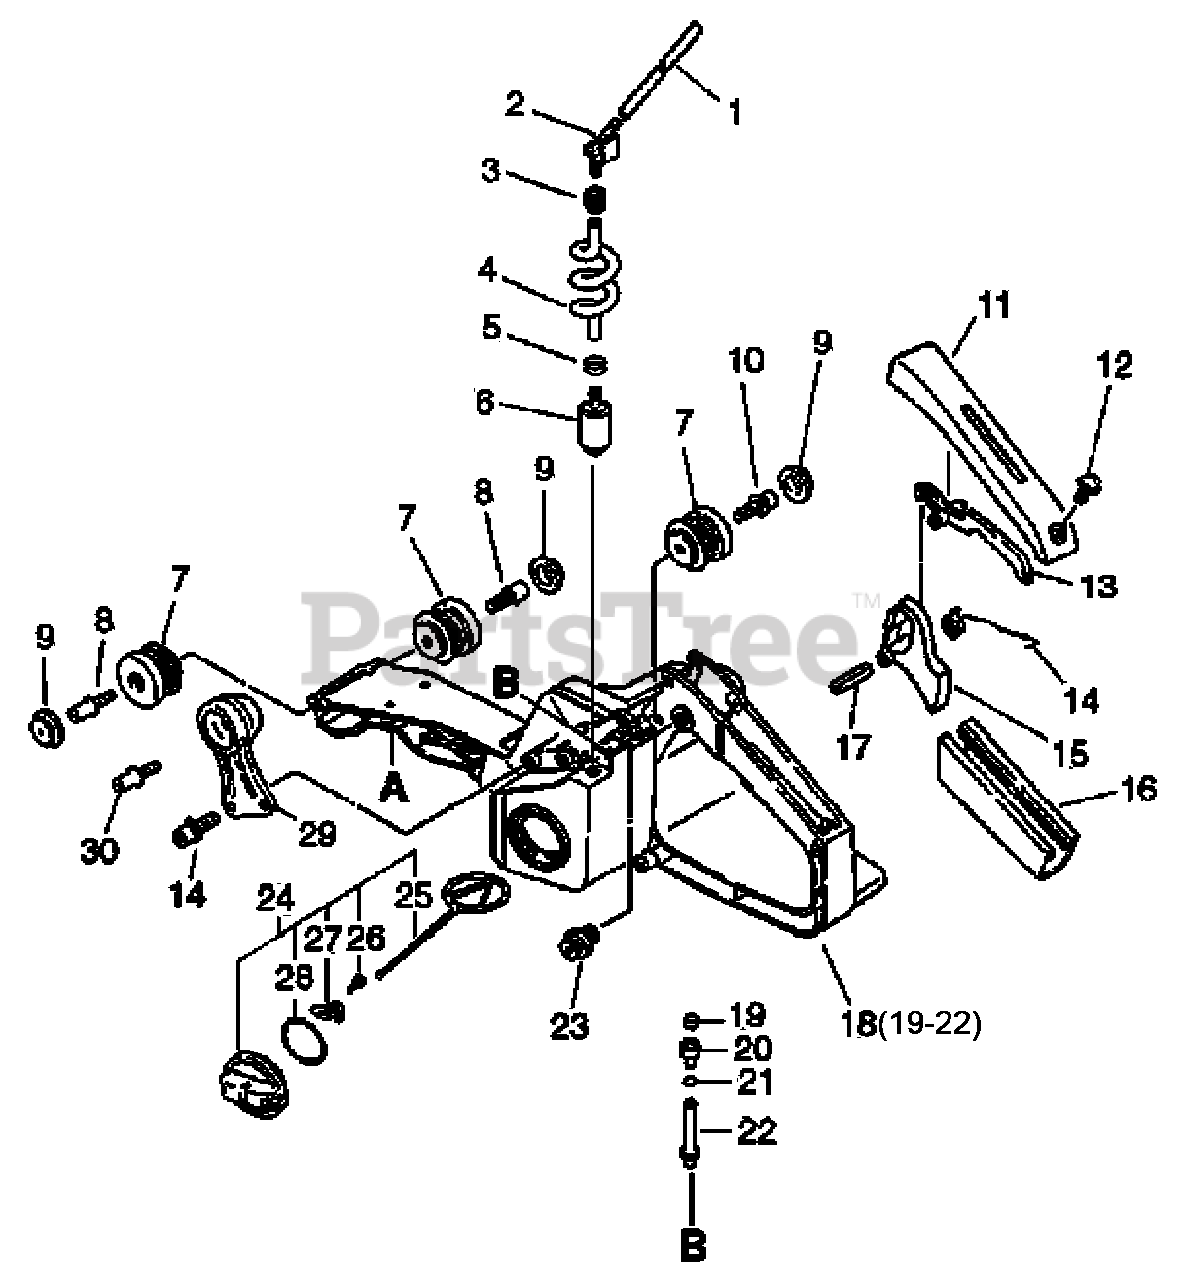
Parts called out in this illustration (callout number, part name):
1	PIPE - 3X6X100 -- BLACK
2	CONNECTOR, PIPE
3	GROMMET
4	PIPE - BLACK
5	CLIP - 6.5
6	FILTER, FUEL
9	CAP, CUSHION
10	SCREW - 5X14
11	COVER, HANDLE
12	SCREW - 4X14
13	LOCKOUT, THROTTLE
14	SPRING, TRIGGER
15	TRIGGER, THROTTLE
16	GRIP, HANDLE
17	PIN - SPRING -- 5X25
18	HANDLE - REAR
19	VENT, FUEL TANK
20	COVER, VENT
21	CLIP - 6.5
22	PIPE - VENT
23	LATCH, THROTTLE
24	CAP ASSY
25	CONNECTOR, CAP
26	SCREW - 3X8
27	RETAINER
28	O-RING - 29
